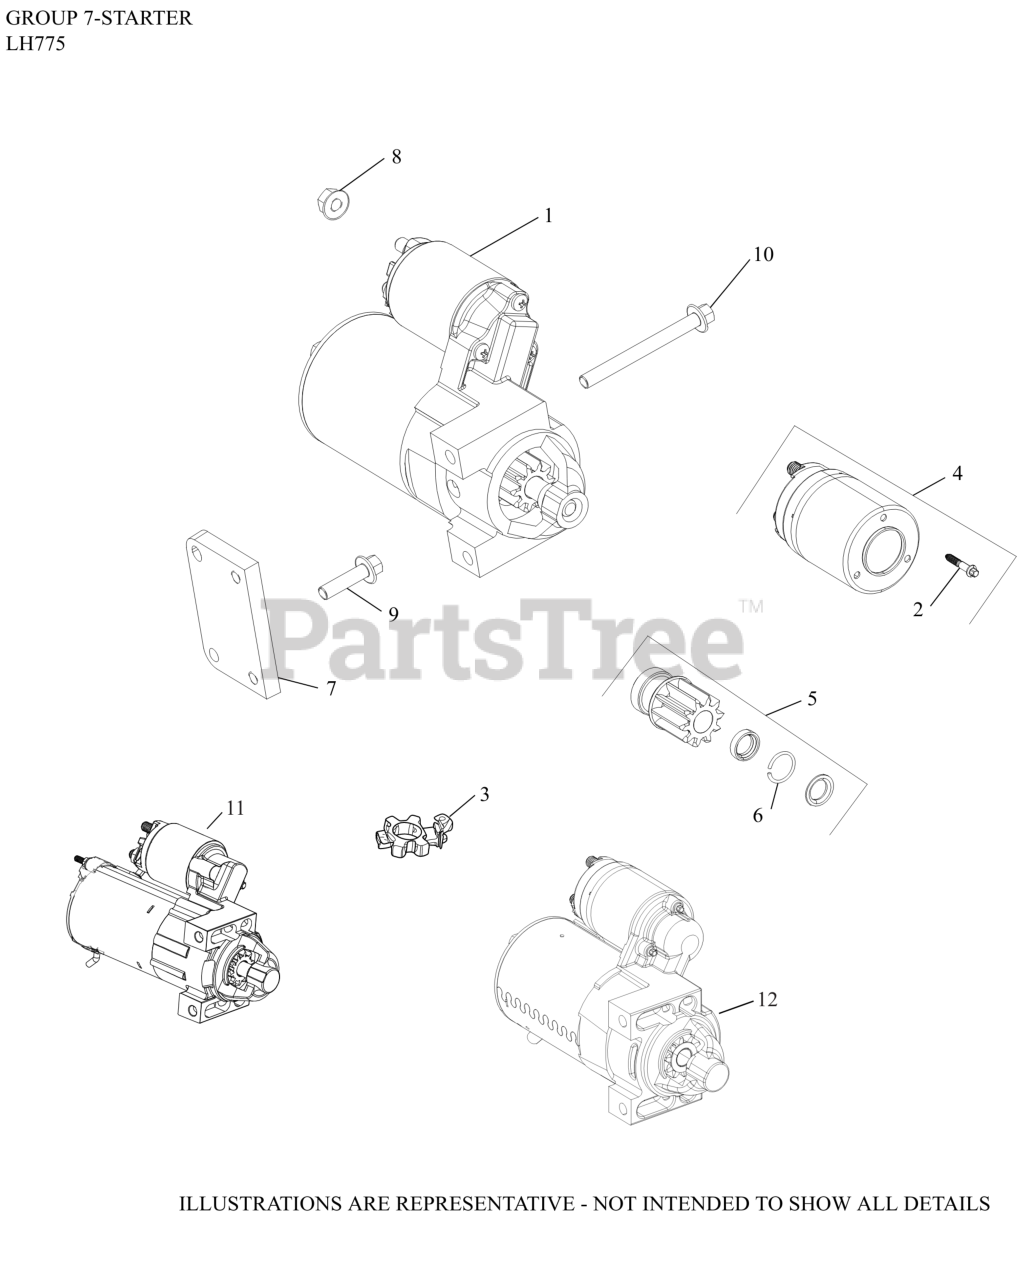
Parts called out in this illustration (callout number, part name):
7	PLATE, STARTER
8	NUT, FLG M8X1.25
9	SCREW, FLG M8X1.25X30
10	SCREW, FLG M8X1.25X80
12	STARTER, SOLENOID SHIFT-(#2509824S)
